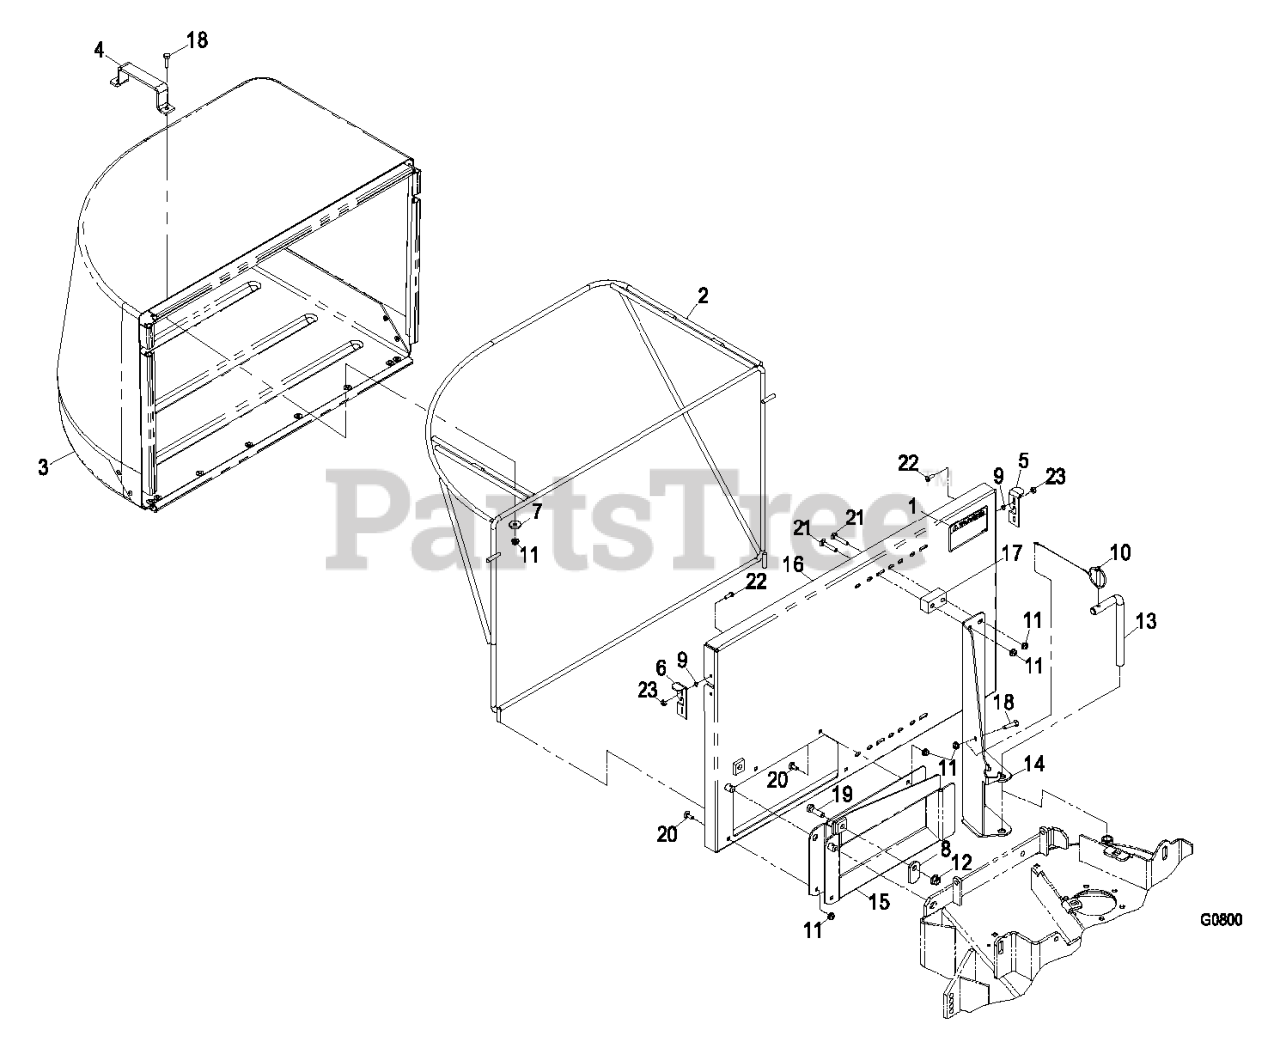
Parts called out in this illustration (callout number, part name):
1	DECAL-WARNING, DISCHARGE
2	FRAME-CATCHER
5	LATCH-CATCHER, LH
6	LATCH-CATCHER, RH
8	LATCH-CATCHER, GRASS
9	WASHER-SPRING
10	PIN ASM-LYNCH
12	NUT-HF, NI
13	PIN,SUPPORT
15	WELD,ADAPTER
16	ASM,BACKING PLT W/DECAL
17	Block, Spacer
18	SCREW-HH
19	SCREW-HH
20	SCREW-CARR
21	SCREW-CARR
22	SCREW-PPH
23	NUT-LOCK, NI
